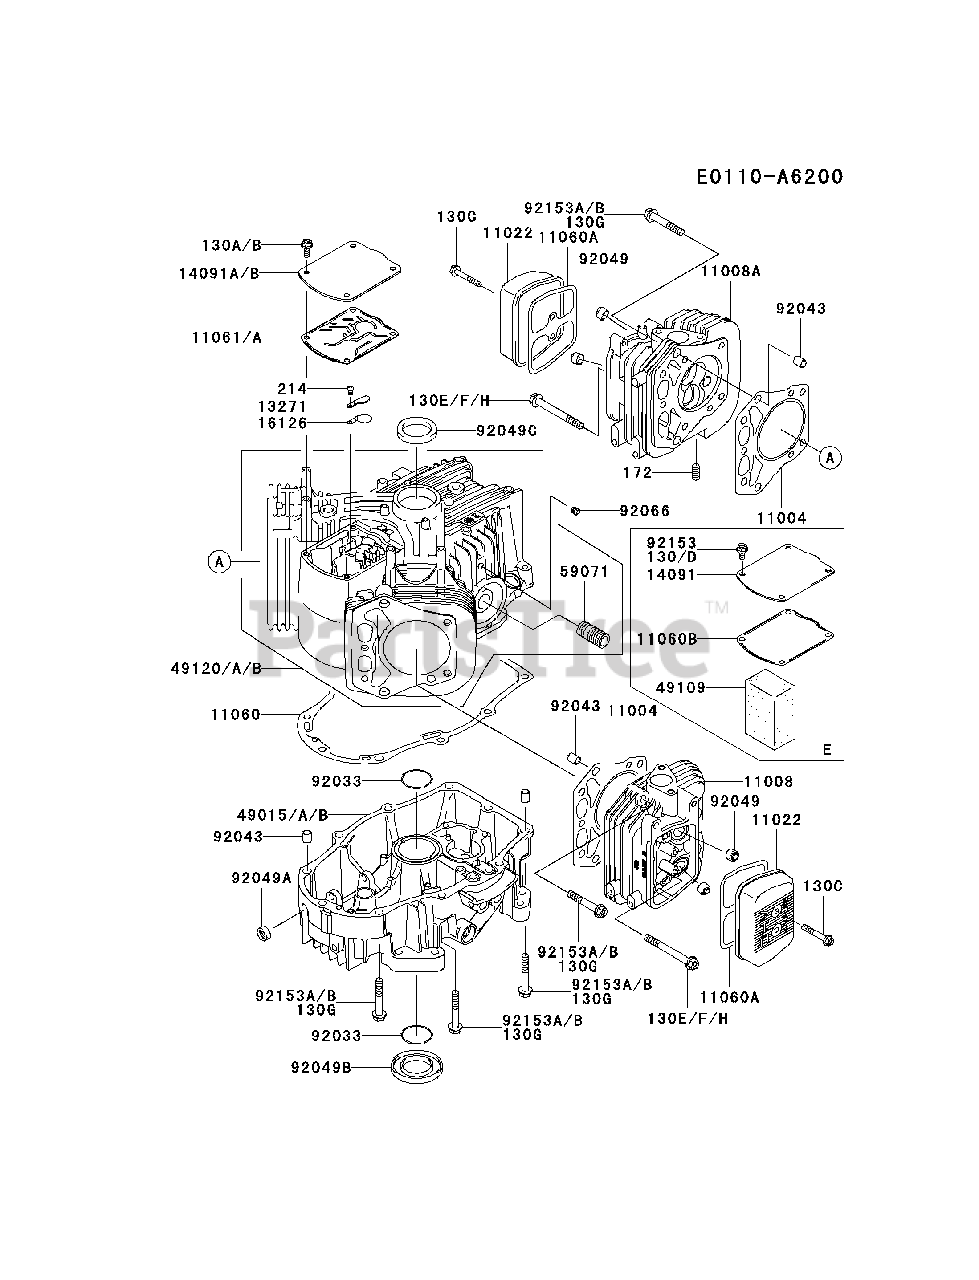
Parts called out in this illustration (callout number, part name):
130B	BOLT-FLANGED,6X16
130C	BOLT-FLANGED,6X40
130D	BOLT-FLANGED,6X12
130F	BOLT-FLANGED,8X75
130G	BOLT-FLANGED,8X50
130H	BOLT-FLANGED,8X75
172	BOLT-STUD,8X18
214	SCREW-PAN+-,4X8
